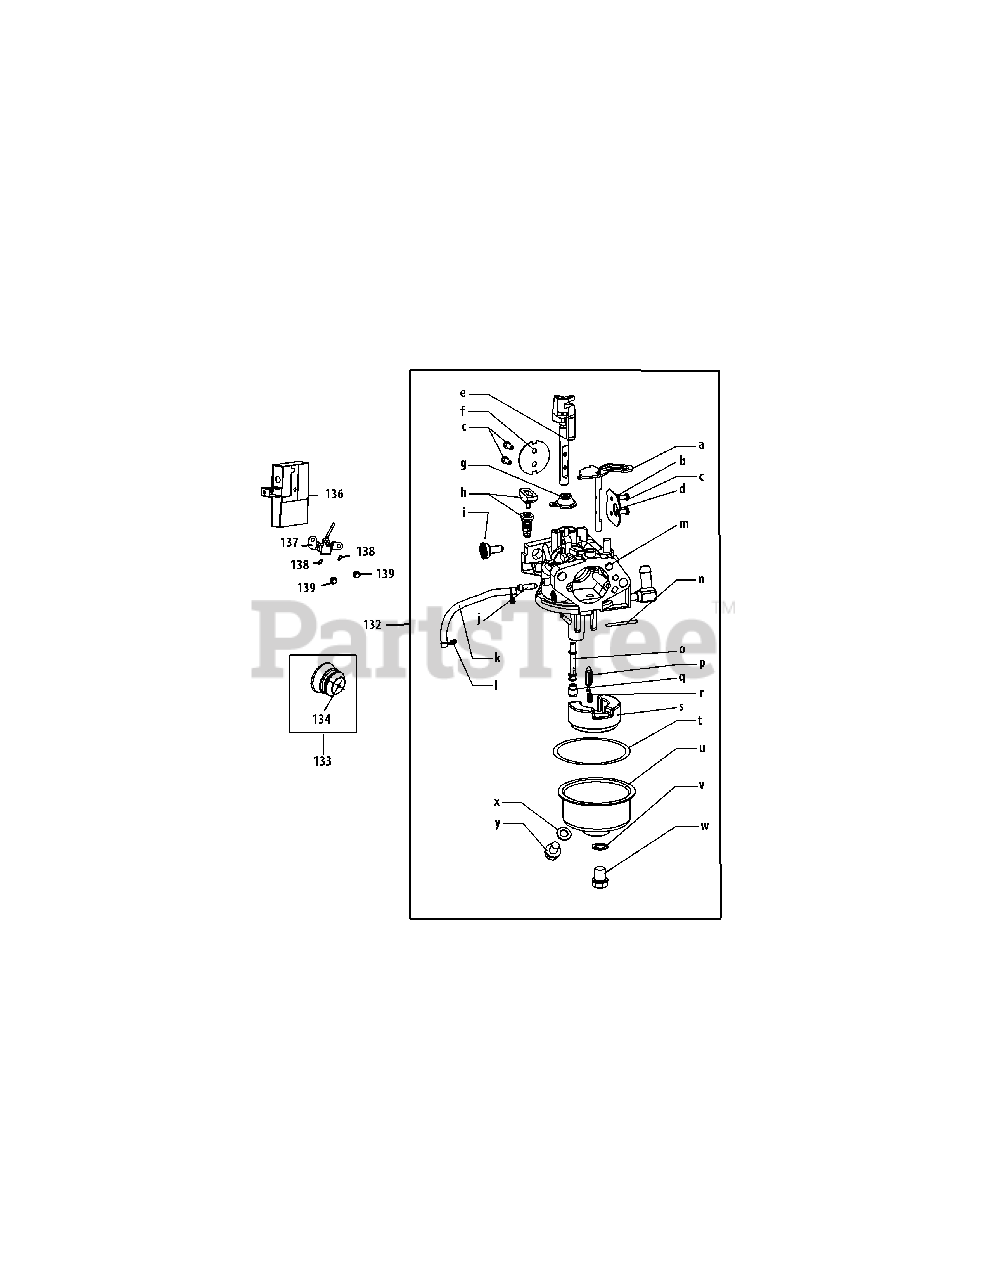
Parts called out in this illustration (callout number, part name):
132	Carburetor Assembly
133	Primer Assembly
134	Primer Bulb
